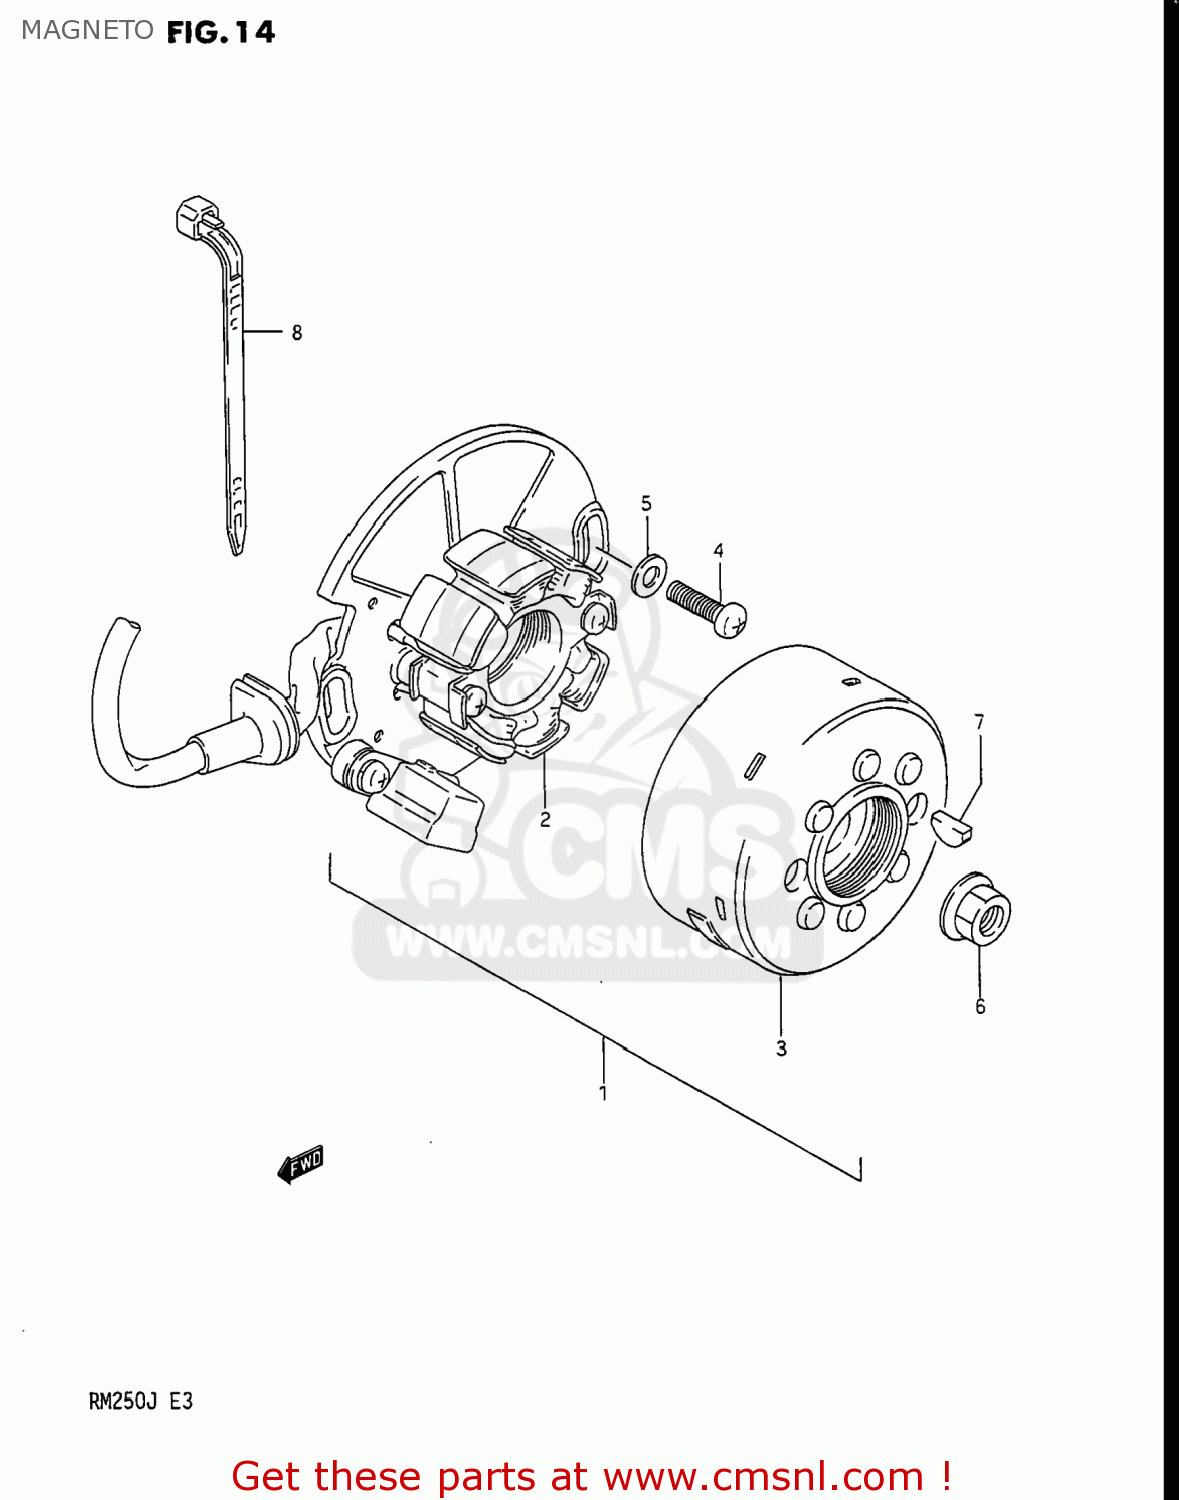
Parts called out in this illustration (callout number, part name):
1	MAGNETO ASSEMBLY
2	STATOR ASSEMBLY
3	ROTOR
4	SCREW
5	WASHER
6	NUT
7	KEY 4MM
8	CLAMP(L:125)
